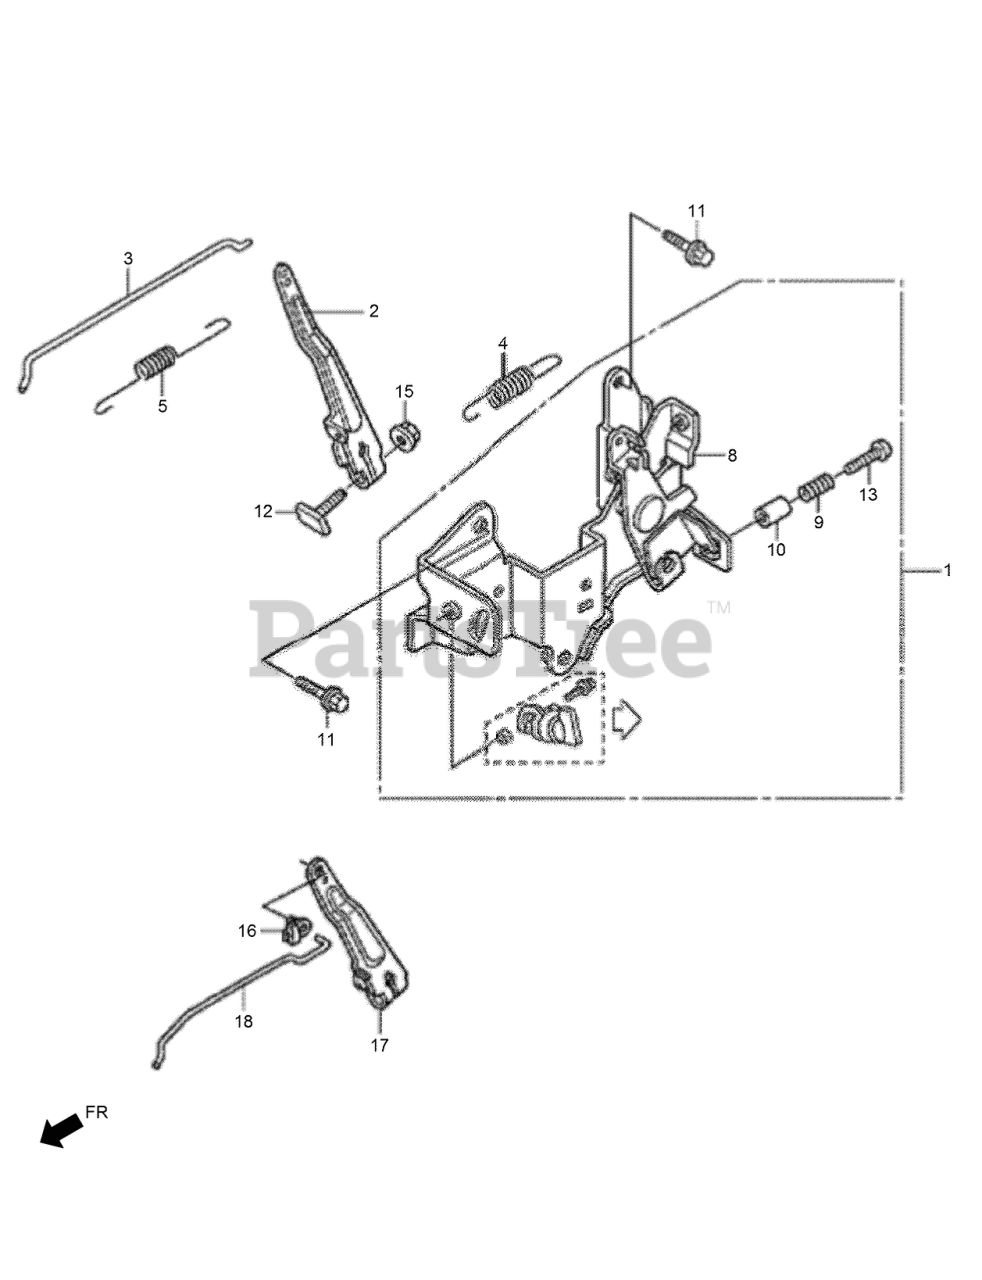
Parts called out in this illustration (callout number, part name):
1	CONTROL ASM
2	ARM-GOVERNOR (to S/N 1000526)
3	ROD-GOVERNOR (to S/N 1000526)
4	SPRING-GOVERNOR
5	SPRING-THROTTLE RETURN
8	CONTROL BASE ASM
9	SPRING-CONTROL ADJUSTING
10	COLLAR-STOPPER
11	BOLT-FLANGE-5X12
12	BOLT-GOVERNOR ARM
13	SCREW-RECESSED-5X28
15	NUT-FLANGE-6MM
16	JOINT-ROD (from S/N 1000527)
17	ARM-GOVERNOR (from S/N 1000527)
18	ROD-GOVERNOR (from S/N 1000527)
